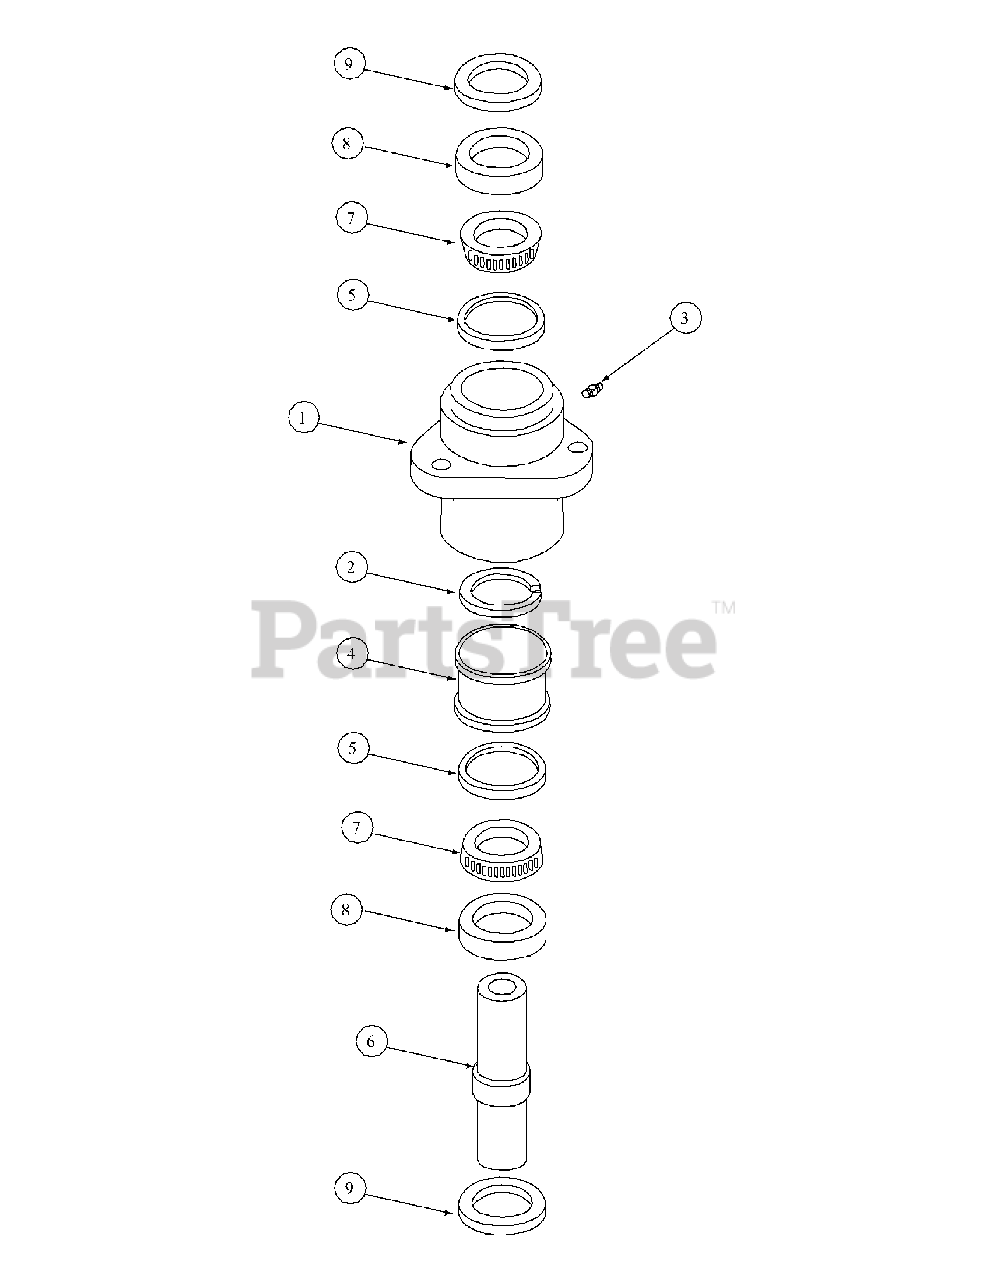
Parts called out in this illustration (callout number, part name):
1	Spindle Housing
2	Spacer Bearing
3	Grease Fitting
4	Spacer
5	Cup Bearing
6	Shaft Blade Spindle
7	Cone Bearing
8	Ring Seal
9	Oil Seal
